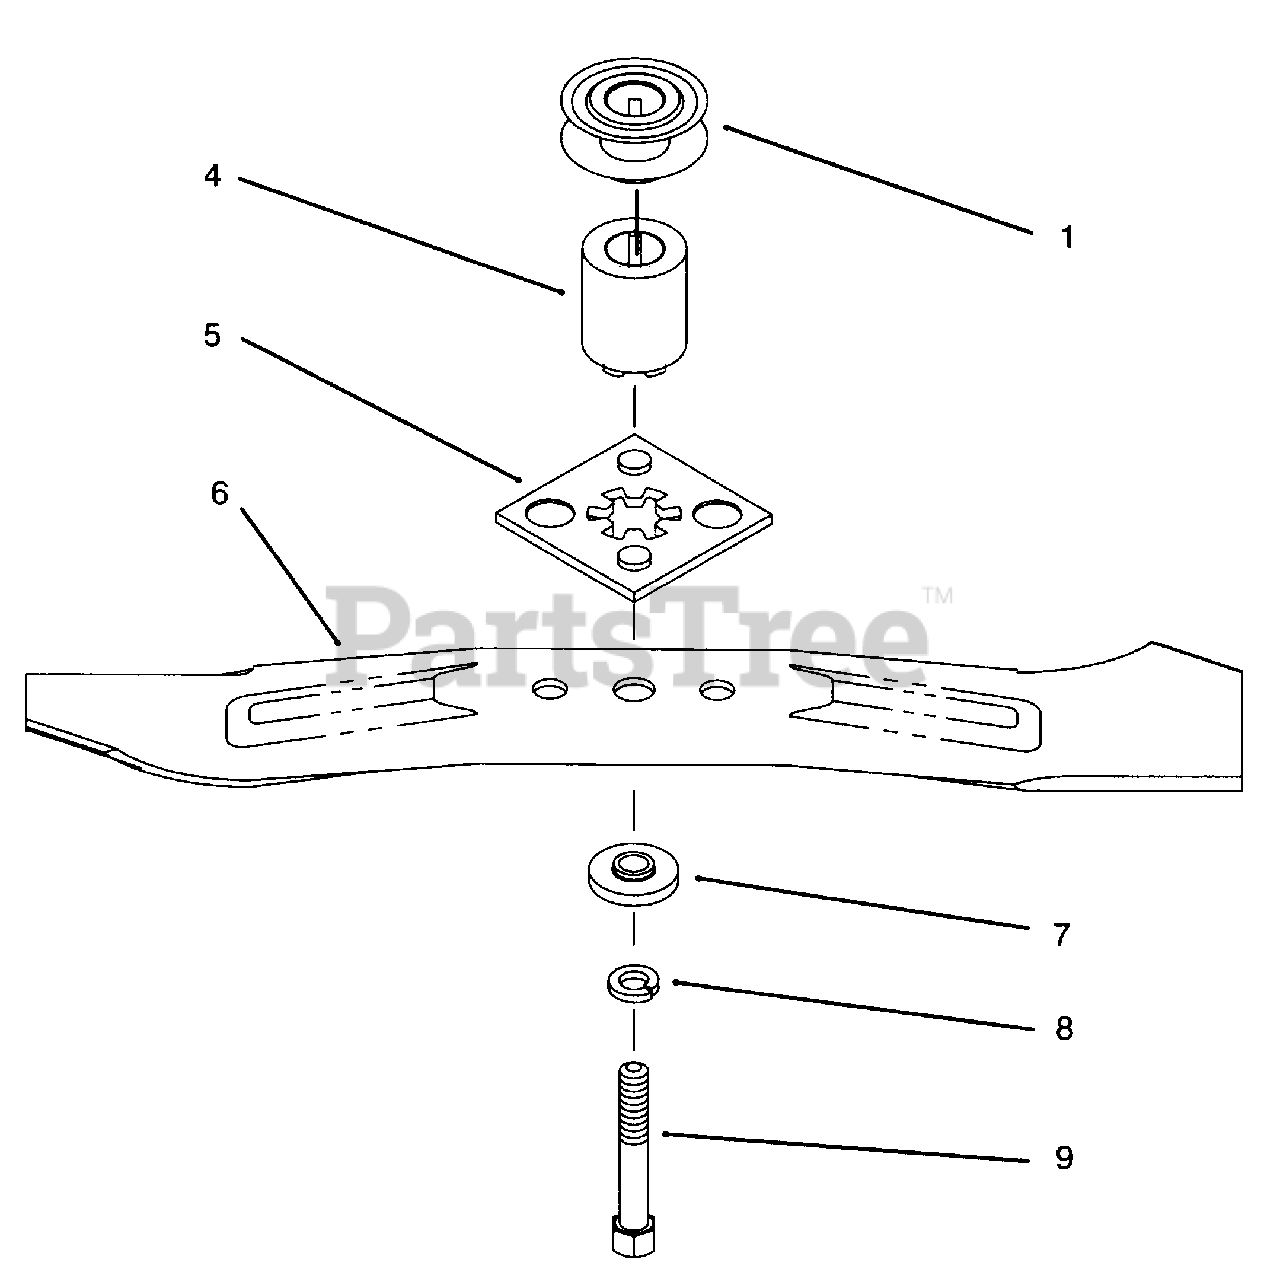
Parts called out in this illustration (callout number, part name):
1	Pulley-Driver
4	Hub-Blade Driver
5	Plate-Blade Driver
6	Blade-48cm
7	Spacer-Blade
8	Washer-Lock
9	Bolt-Blade
